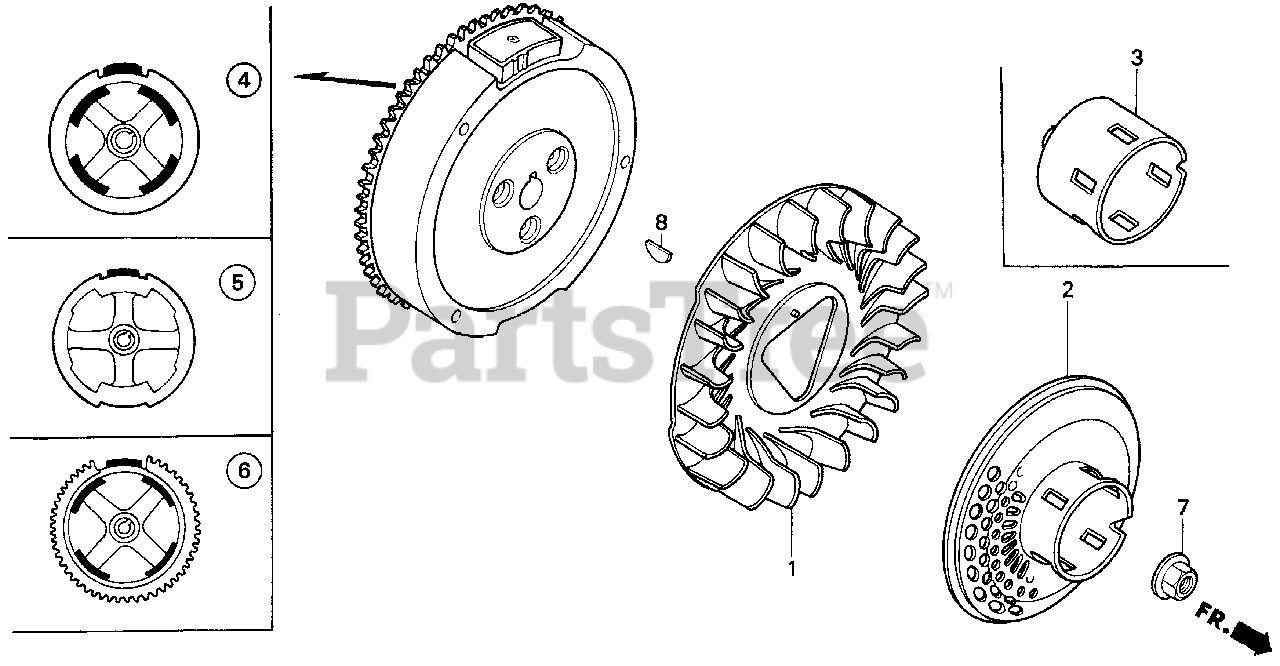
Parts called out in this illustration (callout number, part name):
1	FAN, COOLING
2	PULLEY, STARTER (SCREEN GRID)
5	FLYWHEEL
7	NUT, SPECIAL (16MM) (1)
7	NUT, SPECIAL (16MM)
8	KEY, SPECIAL WOODRUFF (25X18)
